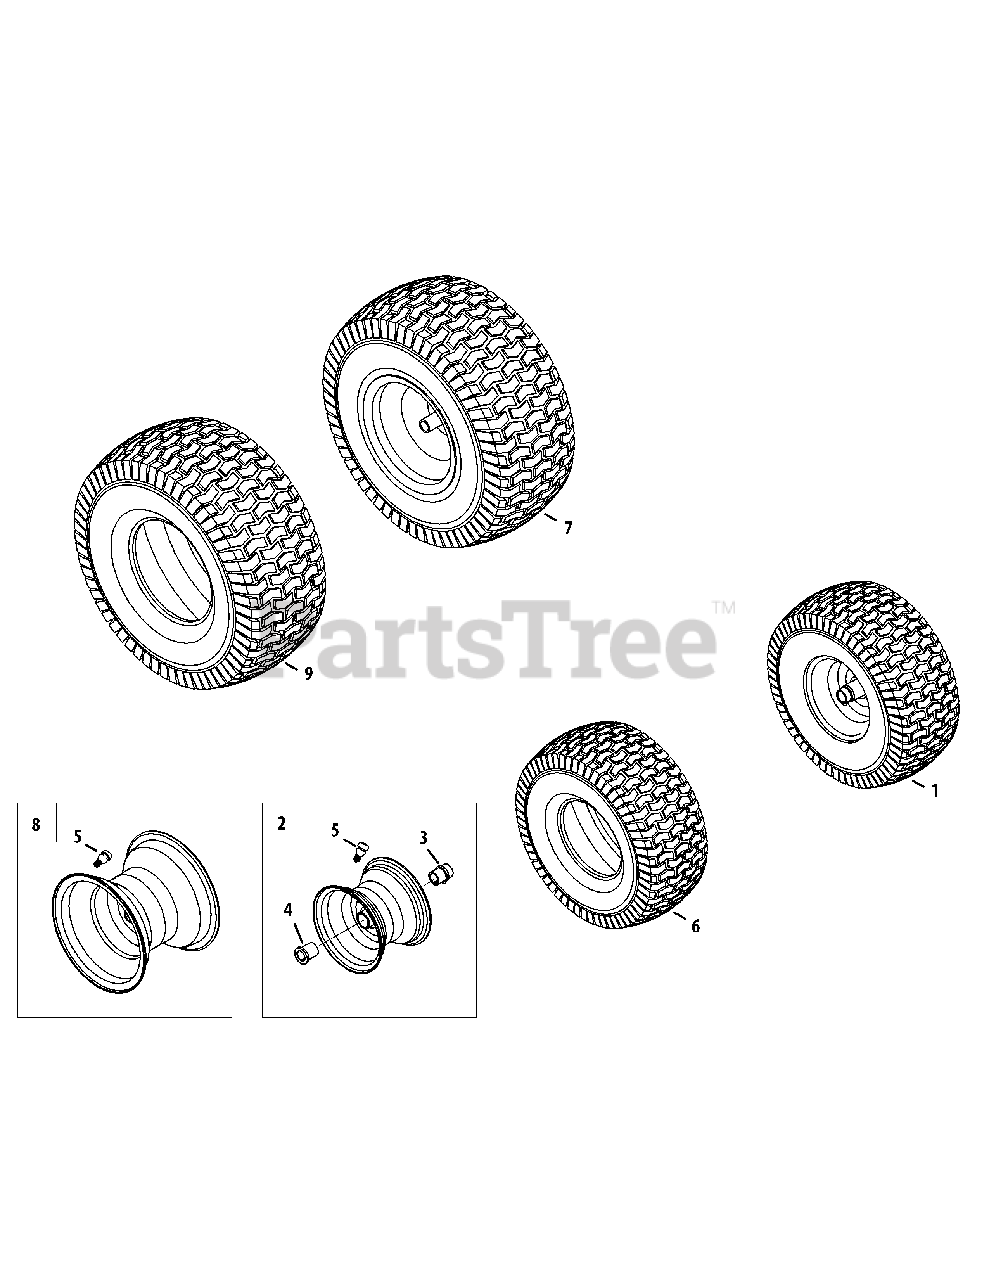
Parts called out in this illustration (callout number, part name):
1	Wheel Ass’y, Complete, 15 x 6 x 6
2	Rim Ass’y, 6.0 x 4.5, Flange Bearings
3	Bearing, Flange, .760 ID w/ Fitting
4	Bearing, Flange, .760 x 1.00 x 1.20
5	Valve, Tubeless Air
6	Tire, 15 x 6 x 6 Sq Shoulder
7	Wheel, Complete, 20 x 8 x 8
8	Rim Ass’y, 8.0 x 7.0 x .750 ID
9	Tire, 20 x 8 x 8 Sq Shoulder
